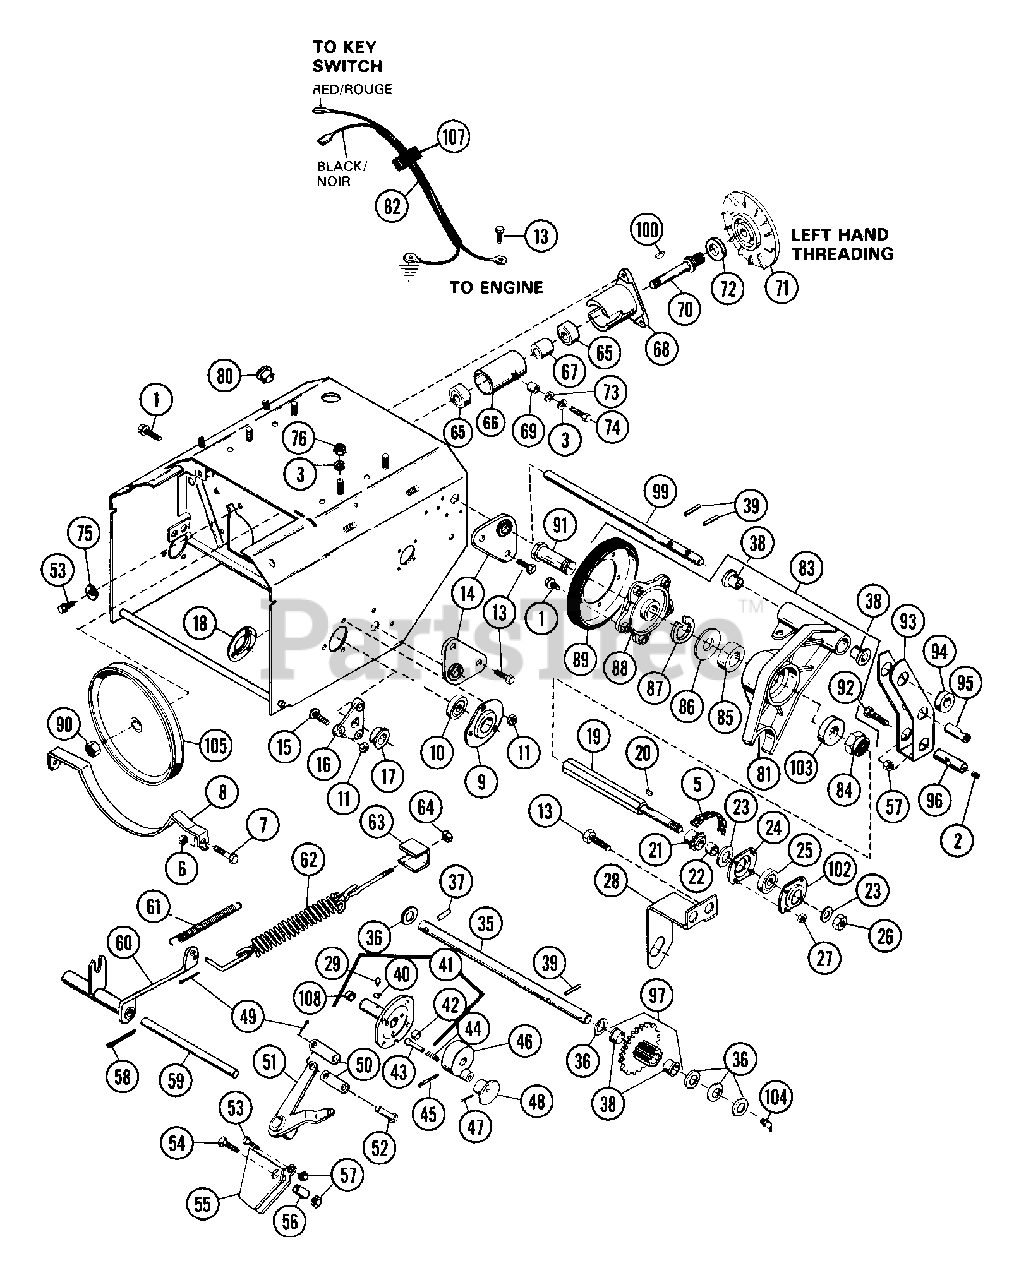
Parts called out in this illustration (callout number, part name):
1	BLT-SERHFWH .31-18X.50 PL
2	SCR-SET .32-18X.38 SKHCUPNL OH
3	WSHR-LK .312X.097 PL HVY
5	CHAIN
6	NUT-LK-CTR .250-20 PL
7	BLT-HEX .25-20X.50 PL GR2
8	BELT RETAINER
9	BEARING FLANGE
10	BRG-BALL .876 X 1.750 X .50
11	NUT-LK-FLG .250-20 PL
13	BLT-SERHFWH .25-20X.50 PL
14	SUPPORT, SHAFT
15	SCR-SLTR-SERNK .25-20X.62 PL
16	SUPPORT, BEARING
17	BSHG-FLG .750X1.000X.625X1.250
18	BEARING FLANGE
19	HEX SHAFT
20	KEY-WDRF .125X.625X.250 SAE5
21	9 TOOTH SPROCKET
23	WSHR-FL-STL .505X1.000X.062
24	BEARING FLANGE
25	BRG-BALL .500X1.38X.437
26	NUT-LK-CTR .50-20 PL
27	NUT-LK DUAL FACE 10-24 PL
28	CLUTCH STOP
29	SPIN DRIVE ZERK FITTING
35	PINION SHAFT
36	WSHR-FL-STL .630X1.005X.062 PL
37	PIN-ROLL .125X1.00
38	BSHG-FLG .625X.750X.500X.875BR
39	PIN-ROLL .156X1.00
40	WSHR-LK .250X.047 LT PL
41	L H AXLE ASSEMBLY
42	BSHG-SLV .562X.625X.625 BRZ
43	PIN
44	SG-COMP .028X.34X1.062 WLD75
45	PIN-GRV .250X1.75 TP C
46	LOCKOUT HUB
47	PIN-ROLL .093X1.00
48	KNOB
49	PIN-COTR .09X.75 PL
50	SHIFT LINK
51	LEVER - SHIFT ARM
52	CLEVIS PIN
53	BLT-HEX .31-18X.50 PL GR2
54	BLT-HEX .31-18X3.00 PL GR2
55	BRACKET SHIFT LEVER
56	SPACER .5 X .33 X 2.4
57	NUT-LK .312-18 GR A PL
58	PIN-COTR .09X1.0 PL
59	ROD, FORK PIVOT
60	FORK, CLUTCH
61	SG-TENS .080X.73X3.06 WLD 20
62	SPRING ASSEMBLY
63	ADAPTER SPACER
64	NUT-LK-NYL.312-18 PL
65	BRG-BALL .625X1.375X.44
66	SPINDLE HOUSING
67	BEARING SPACER
68	DRIVE SPINDLE HOUSING
70	SPINDLE
71	DRIVE PLATE
72	DRIVE DISC SPACER 1.3X.76X.19
73	WSHR-FL-STL.344X.688X.065PL
74	BLT-HEX .31-18X1.00 PL GR 2
75	WSHR-LK-INT .313X.030 PL
76	NUT-HEX .312-18
80	BUTTON PLUG 1.0
81	CARRIER
82	SHORTING WIRE
83	FRICTION WHEEL ASSEMBLY
84	NUT-LK-NYL .875-14
85	BRG-BALL .876 X 1.750 X .50
86	WSHR-FL-STL .880X1.250X.062
87	RG-RTNG-INT 1.750X.062
88	DISC HUB
89	FRICTION DISC
90	NUT-LK-NYL.625-18 PL
91	SPINDLE HUB
92	BLT-HEX .31-18X.75 PL GR2
93	CLUTCH ENGAGEMENT YOKE
94	SPACER 1.00 X .64 X .38
95	ADAPTER
96	ROD ADAPTER
97	PINION AND SPROCKET ASSY.
99	CARRIER SHAFT
100	KEY-WDRF .125X.500X.203 SAE 3
102	BEARING FLANGE
103	BSHG-SLV .882X1.250X.531
104	HYDRAULIC DRIVE FITTING
105	PLY-V 8.00 X 1.0 W/KEY CLARK
108	BSHG-SLV .750X.814X .750 BRZ
